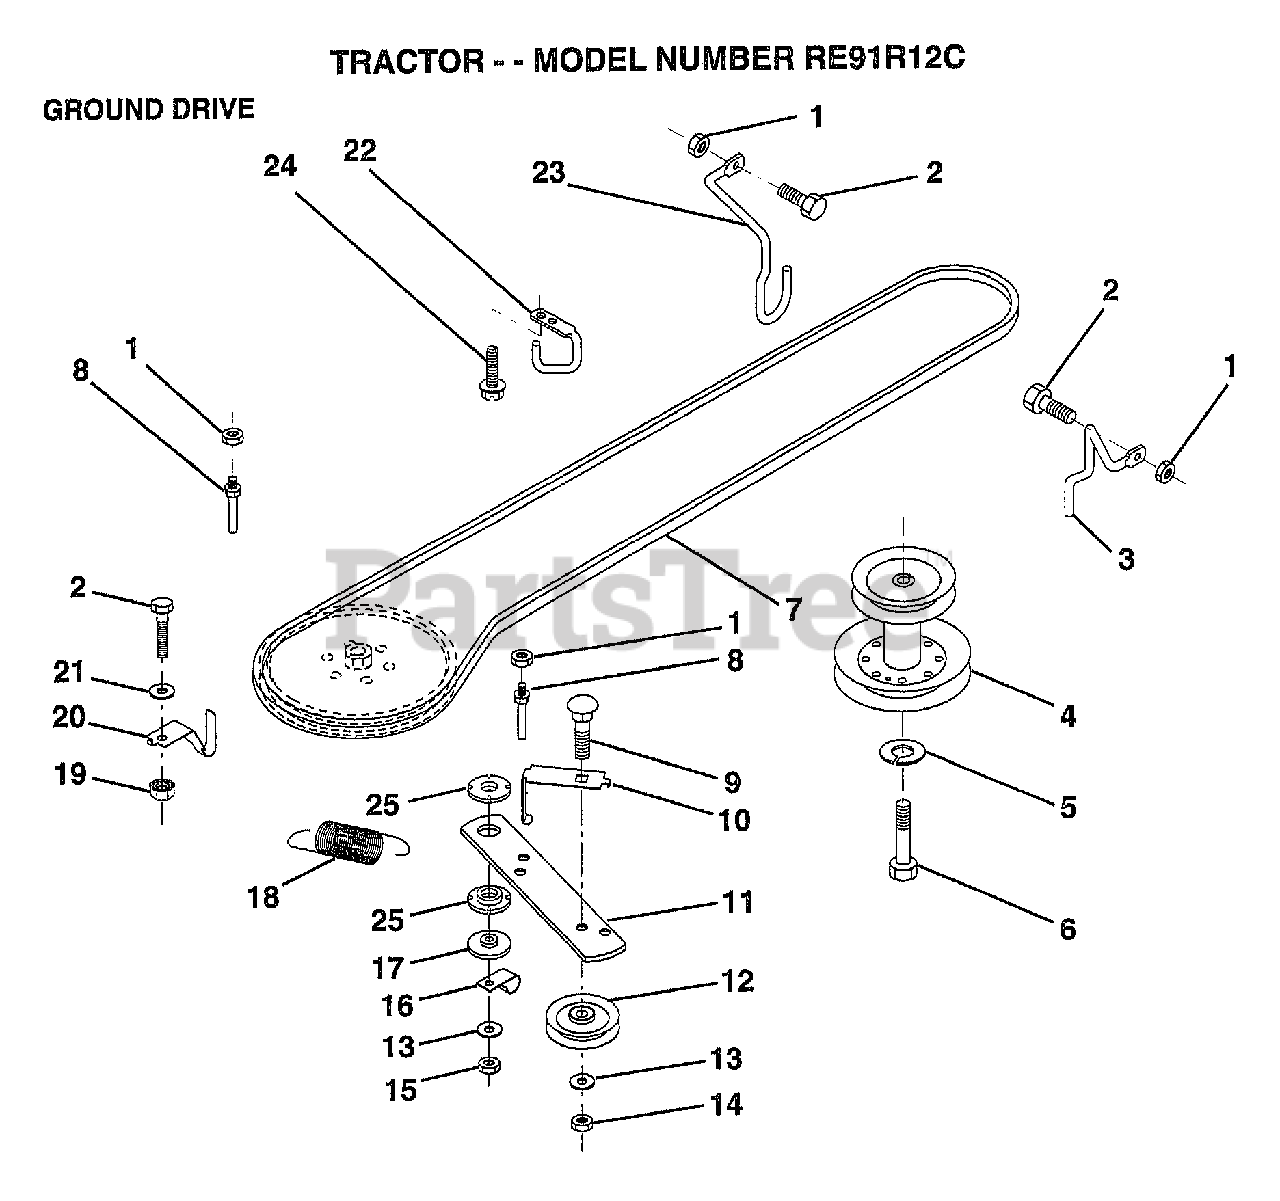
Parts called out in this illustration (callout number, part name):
2	BOLT
3	KEEPER RH
4	PULLEY.ENGINE.LR
5	LOCKWASHER
6	HEX BOLT
7	V BELT
8	"KEEPER,DRIVE BELT"
9	BOLT
10	"KEEP,IDLER DR BEL"
11	ARM-IDLER.DR.GRND
12	PULLEY.IDLER.FLAT
13	WASHER
14	LOCKNUT
16	"CLIP,INSULATOR"
17	SPACER
20	KEEPER.BELT.T/A
21	WASHER
22	"KEEPER,FRA DR BEL"
23	KEEPER MOWER LH
24	SCREW
25	BUSHING.NYLON
